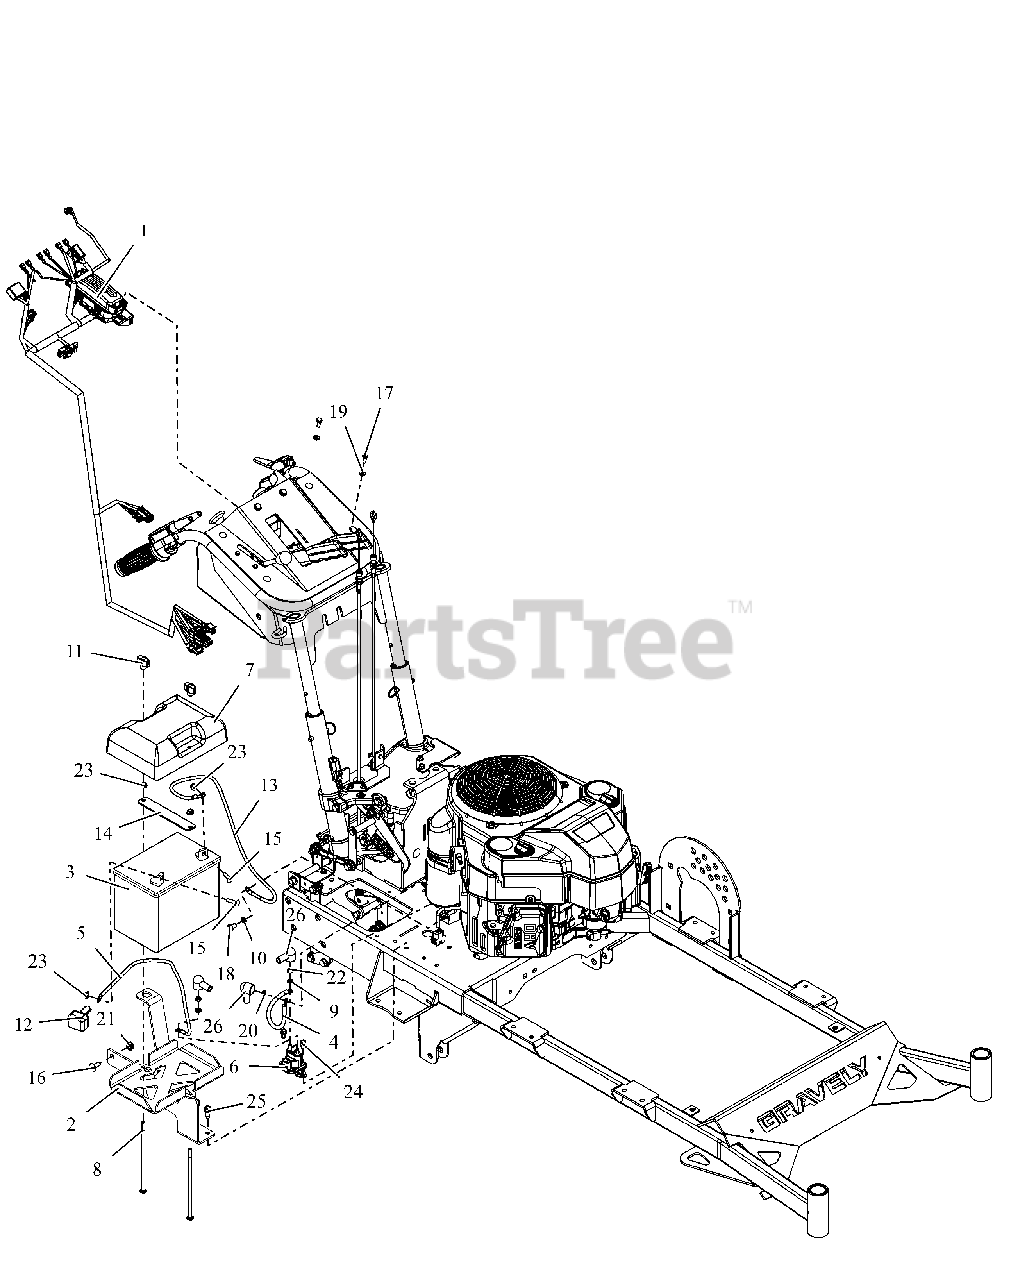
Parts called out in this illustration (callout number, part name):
1	HARNESS, HYDRO PROWALK
2	WLDMT, BATTERY TRAY
3	BATTERY, 300 CCA 10U1L
4	CABLE-POSITIVE BATTERY 9.00"
5	CABLE - START 22.00"
6	SOLENOID, STARTER (SEALED)
7	COVER, BATTERY
8	@BLT-RDHDSQNK .25-20X7.00 G2YZ
9	@WSHR-LK-EXT.262X.502X.026YWZC
10	@WSHR-LK-EXT.326X.599X.031YWZC
11	KNOB, WING - .25-20 UNC
12	INSULATOR
13	CBL,NEGATIVE BATTERY 20.00
14	STRAP, BATTERY
15	@BLT-RDHDSQNK .25-20X1.00 G5YZ
16	@BLT-RHDSSQNK .31-18X.75 G5YZ
17	@BLT-HEX M6-1X16 YWZC
18	@BLT-HEX M8 X 1.25X14 YWZC
19	@WSHR-LK .25X.062 REG YWZC
20	NUT, HEX-JAM M6-1.0 G8.8 ZCC
21	@NUT-LK-CTR-FLG .31-18 YZ GR F
22	NUT-HEX M6X1.0 YWZC
23	@NUT-SPNLK-FLG .25-20 YWZC
24	SCR-TAP .25-20X.50 HWH TR YWZ
25	@SCR-TAP .31-18X.75 HWH TR YWZ
26	BOOT, EYELET TERMINAL
